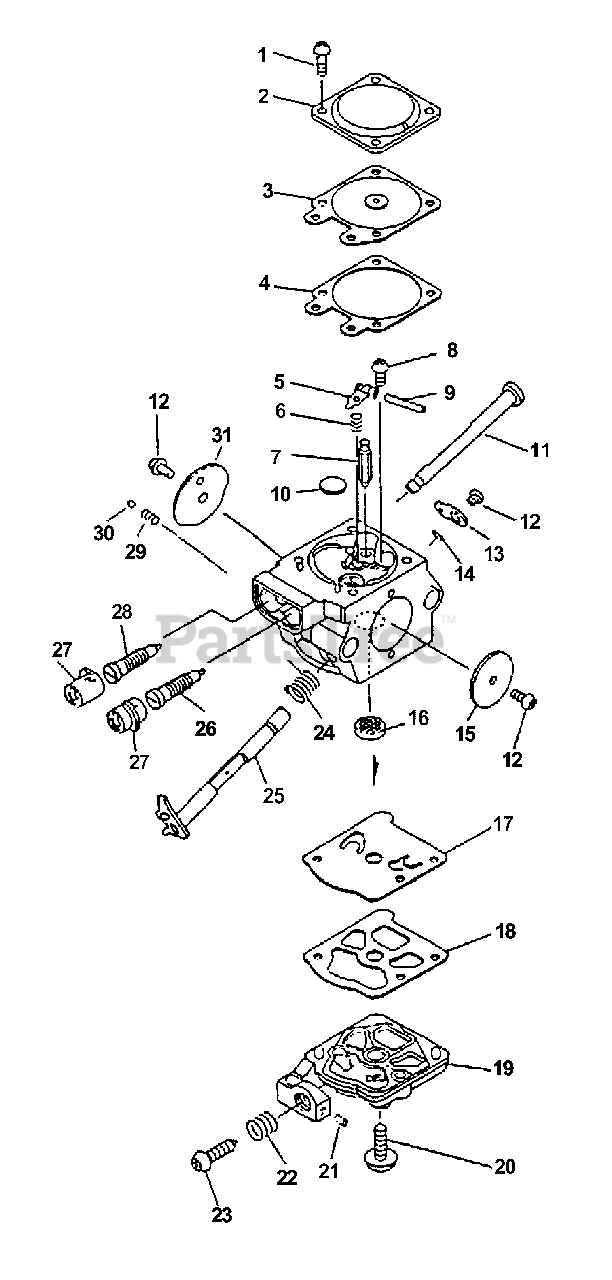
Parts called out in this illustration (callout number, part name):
1	SCREW
2	COVER, METERING DIAPHRAGM
3	DIAPHRAGM, METERING
4	GASKET, METERING
5	LEVER, METERING
6	SPRING, METERING LEVER
7	VALVE, INLET NEEDLE
8	SCREW, METERING LEVER PIN
9	PIN, METERING LEVER
10	PLUG, WELCH
11	SHAFT, CHOKE
13	LEVER, THROTTLE
15	VALVE, THROTTLE
16	STRAINER
19	COVER, FUEL PUMP
21	PLUG, FRICTION
22	SPRING, IDLE ADJUST
23	SCREW, IDLE ADJUST
24	SPRING, THROTTLE RETURN
25	SHAFT, THROTTLE
26	NEEDLE, LOW SPEED
27	CAP, LIMITER
28	NEEDLE, HIGH SPEED
30	BALL, CHOKE FRICTION
31	VALVE, CHOKE
